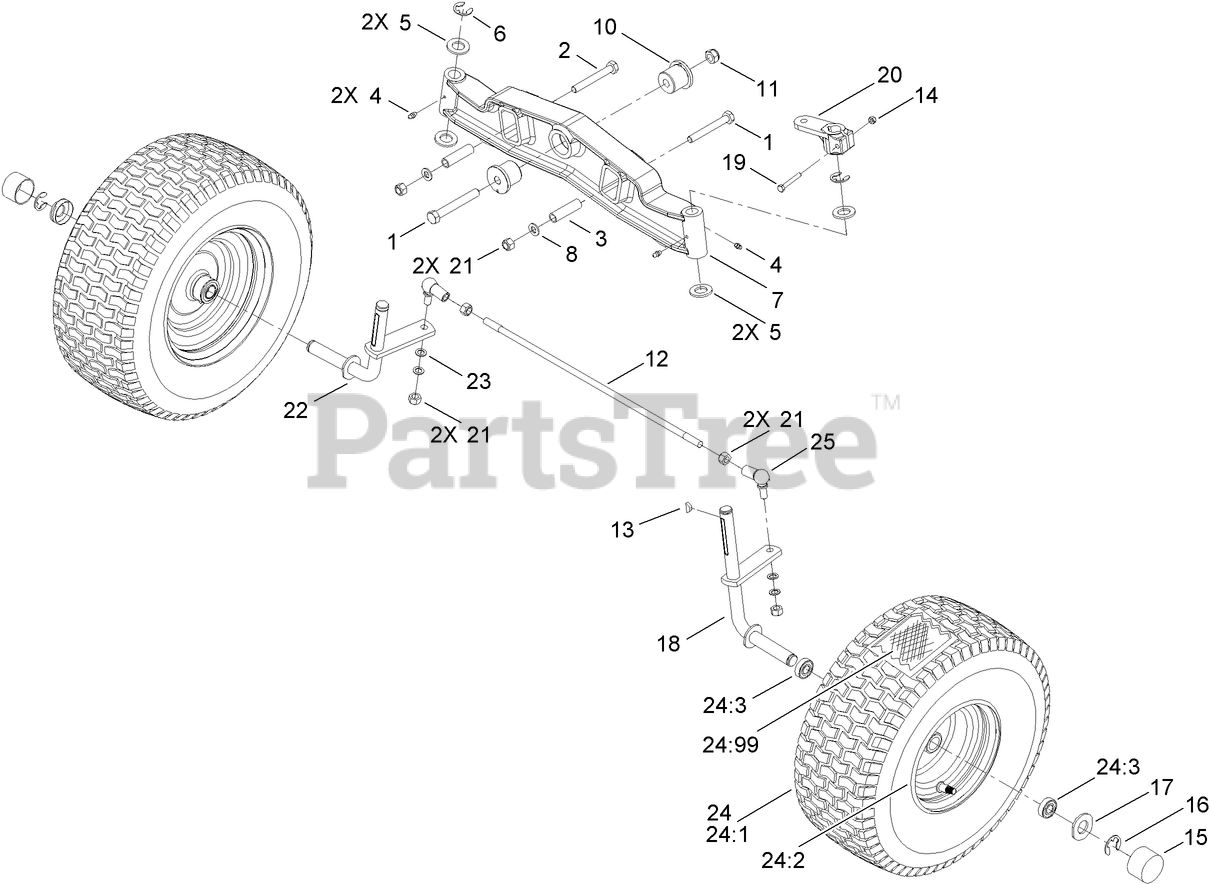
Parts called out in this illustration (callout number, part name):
1	SCREW-HH
2	SCREW-HH
3	SPACER
4	FITTING-GREASE
5	WASHER-FLAT
6	CLIP-SPRING
7	AXLE-FRONT
8	WASHER-FLAT
10	BUSHING-AXLE, FRONT
11	NUT-LOCKING, SELF
12	ROD-TIE, FRONT AXLE
13	KEY-WOODRUFF
14	NUT-LOCK
15	CAP-HUB
16	CLIP-SPRING
17	RETAINER-CAP, HUB
18	SPINDLE-FRONT, LEFT
19	SCREW-HH
20	LEVER-SPINDLE, STEERING
21	NUT-LOCK, NI
22	SPINDLE-FRONT, RIGHT
23	Washer
24	Loose Parts Package
24:2	RIM-FRONT
24:3	BEARING-WHEEL
24:99	TUBE-INNER
25	JOINT-BALL, ANGLE
